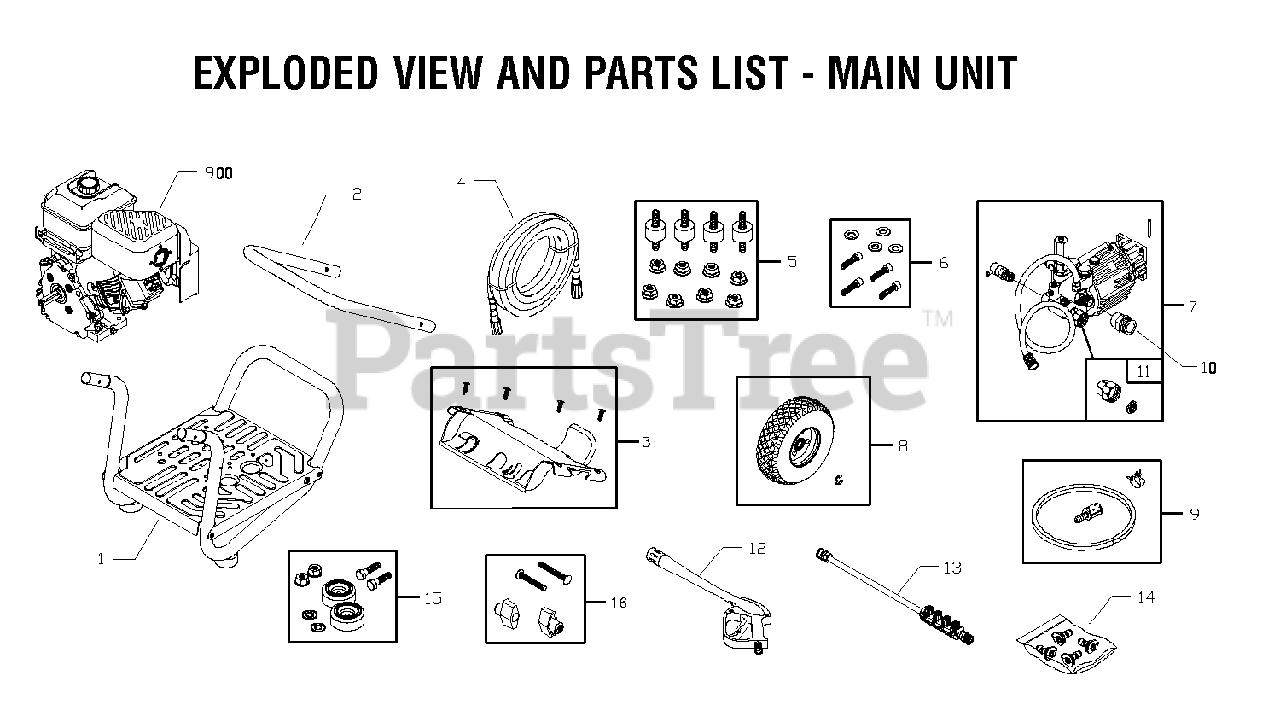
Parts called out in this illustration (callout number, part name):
1	ASSY, Base
3	ASSY, Billboard w/Decal & Clips
4	HOSE
5	KIT, Engine Mounting Hardware
6	KIT, Pump Mounting Hardware
7	ASSY, Pump
8	KIT, Wheel
9	KIT, Chem Hose & Filter
10	CONNECTOR, Garden Hose
11	KIT, Inlet, Hose, Garden
13	EXTENSION, QC w/Nozzle Holder
14	KIT, Nozzles
15	KIT, Vibration Mount
16	KIT, Handle Fasteners
900	§ ENGINE
